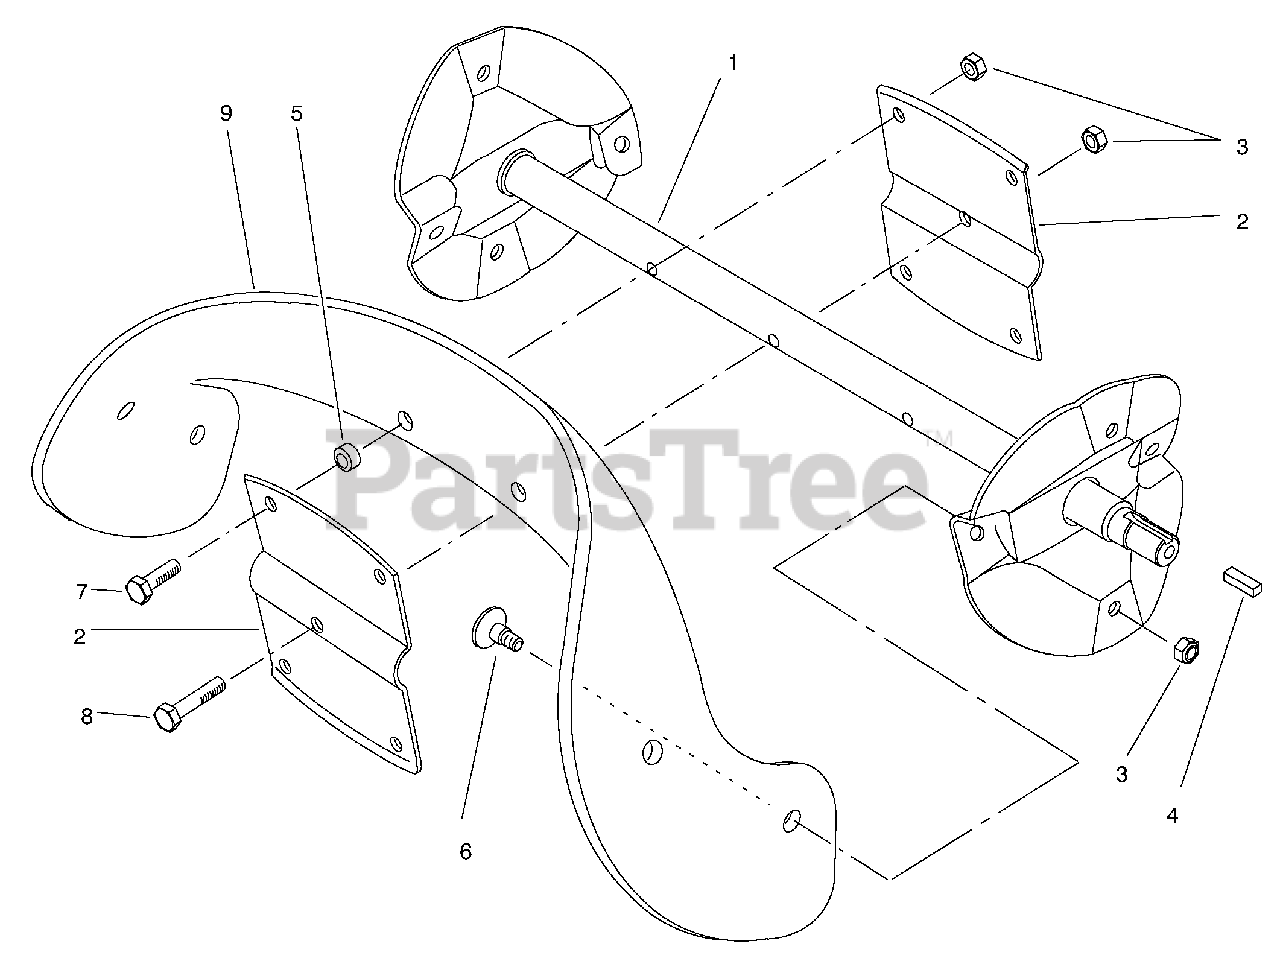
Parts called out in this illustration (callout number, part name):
1	Rotor Shaft Assembly
2	Plate-Rotor
3	Nut-Lock
4	Key-Square
6	Screw-Countersunk
7	Screw-Hex. Hd.
8	Screw-Hex. Hd.
9	Blade-Rotor
